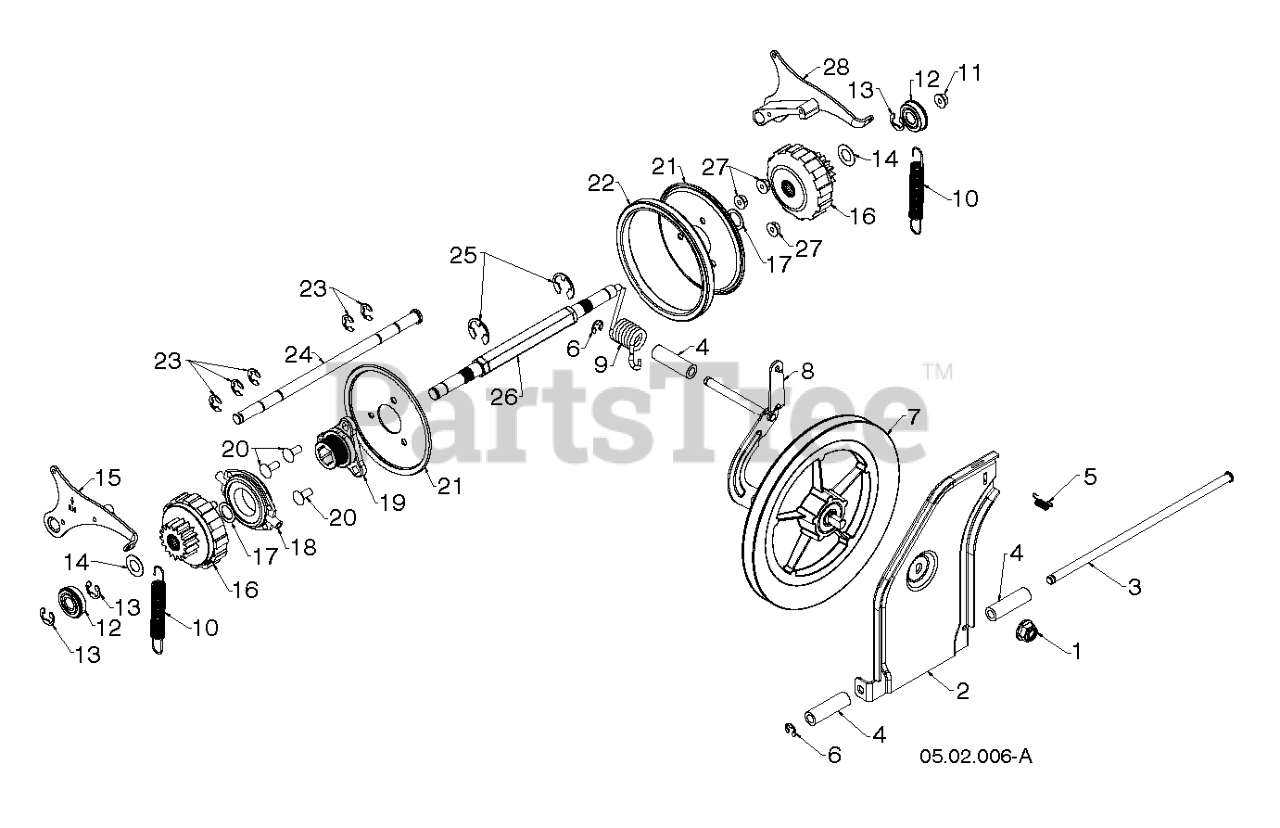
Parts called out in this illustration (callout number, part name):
1	NUT 1/2-13 HEX FLANGE NYLOK CL
3	ROD ROD,PIVOT, SWING PLATE ROD
4	SPACER YOKE, TORSION SPRING
5	SPRING LATCH
6	RETAINER RING E-RING CLEAR ZI
7	PULLEY ASSY TEXTURED TEXTURED
8	BRACKET.YOKE.ASSEMBLY.479
9	SPRING TORSION DRIVE
10	SPRING EXTENSION PS
11	NUT.HEX.FLANGE.LOCK.5/16-18
12	BEARING 9/16 ID. SNR
13	RING.RETAINING.1622-2RSNR.CLER
14	WASHER FLAT.637IDX1.00ODX21GA
15	PAWL.ASM.RH.SNOW
16	GEAR.ASM.PLANETARY
17	WASHER FLAT.59IDX1.065ODX25GA
18	BEARING HOUSING ASSY TRUNNION
19	HUB.RUBBER.WHEEL
20	RHSNB 5/16-18 X 3/4 GR5 BLK ZN
21	PLATE.RUBBER.WHEEL.BLACK
22	Friction Drive
23	CLIP E-RING_.500 SHAFT
24	ROD ROD, PAWL ROD
26	SHAFT SHAFT, PWR STR SHAFT
27	NUT.LOCK.5/16-18
28	PAWL.ASM.LH.SNOW
